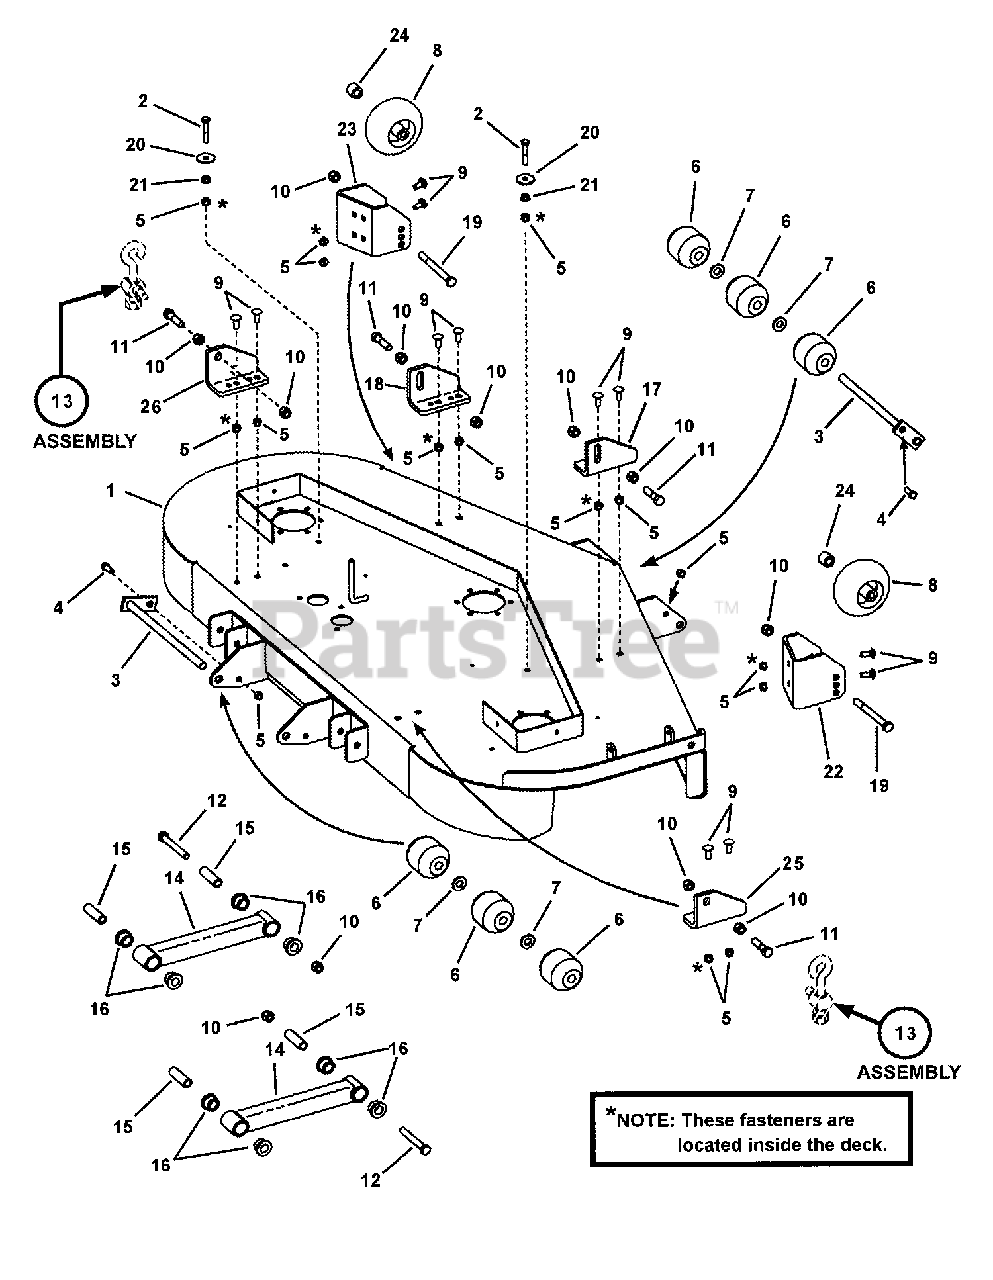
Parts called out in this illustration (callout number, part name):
1	WELDMENT, 61" Deck
2	BOLT, 3/8-16 X 2, GD5, CZ
3	WELDMENT Pivot Pin
4	BOLT, 3/8-16 X 1" GD5 CZ
5	NUT, 3/8-16 HEX NYLON LOCK
6	ROLLER, Low Density Polyethylene
7	WASHER, 5/8" Flat SAE
8	GAUGE WHEEL, Polyethylene
9	BOLT, 3/8-16 x 1" Square Neck Carriage, GR 5
10	NUT, 1/2-13 HEX NYLON LOCK
11	SCREW, 1/2-13 x 2" Hex Head Cap, GR 5
12	BOLT, 1/2-13 x 3-3/4" Hex Head Cap, GR 5
14	WELDMENT, Pusher Bar
15	SLEEVE - Suspension
16	BUSHING - Suspension
17	BRACKET, Deck Lift, Right Hand
18	BRACKET, Deck Lift, Left Hand
19	BOLT, 1/2-13 X 5 GD5 YZ
20	WASHER, .406 x 1.50 x .120 Flat
21	NUT, 3/8-16 HEX SERRATED FLANGE
22	WHEEL BRACKET, Front Right
23	WHEEL BRACKET, Front Left
24	SPACER, Gauge Wheel
25	BRACKET, Deck Lift, RH Rear
26	BRACKET, Deck Lift, LH Rear
